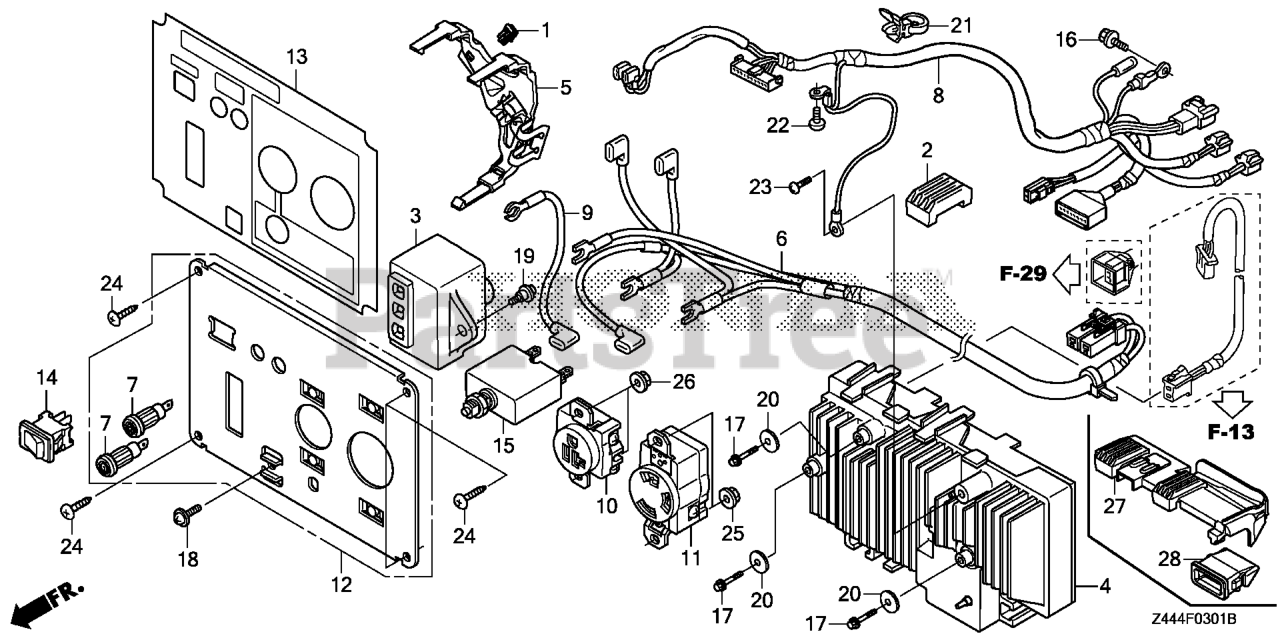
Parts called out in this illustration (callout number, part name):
1	CLIP, TUBE
2	RUBBER B, TANK MOUNTING
3	SPARK UNIT
4	INVERTER UNIT
5	BRACKET, INVERTER HARNESS
6	SUB-WIRE HARNESS ASSY.
7	SOCKET, COMPOSITE
8	WIRE HARNESS ASSY., CONTROL
9	WIRE, TERMINAL
10	RECEPTACLE (20A/125V)
11	RECEPTACLE (3-PRONG) (30A/125V)
12	PANEL, CONTROL
13	MARK, CONTROL PANEL
14	SWITCH, AUTO-THROTTLE (OTAX)
15	PROTECTOR, CIRCUIT (20A) (WHITE)(TYCO)
15	PROTECTOR, CIRCUIT (20A) (BLACK)(JOEMEX)
16	BOLT, FLANGE (5X10)
17	BOLT, FLANGE (5X12)
18	SCREW, PAN (5X12) (GROUND CABLE)
19	SCREW, PAN (5X13)
20	WASHER, PLAIN (20MM)
21	BAND (100MM) (BLACK)
22	SCREW, PAN (5X8)
23	SCREW, PAN (5X10)
24	SCREW, TAPPING (5X16) (PO)
25	NUT, FLANGE (4MM)
26	NUT, FLANGE (4MM)
27	RUBBER B, TANK MOUNTING
28	COVER, CONNECTOR
